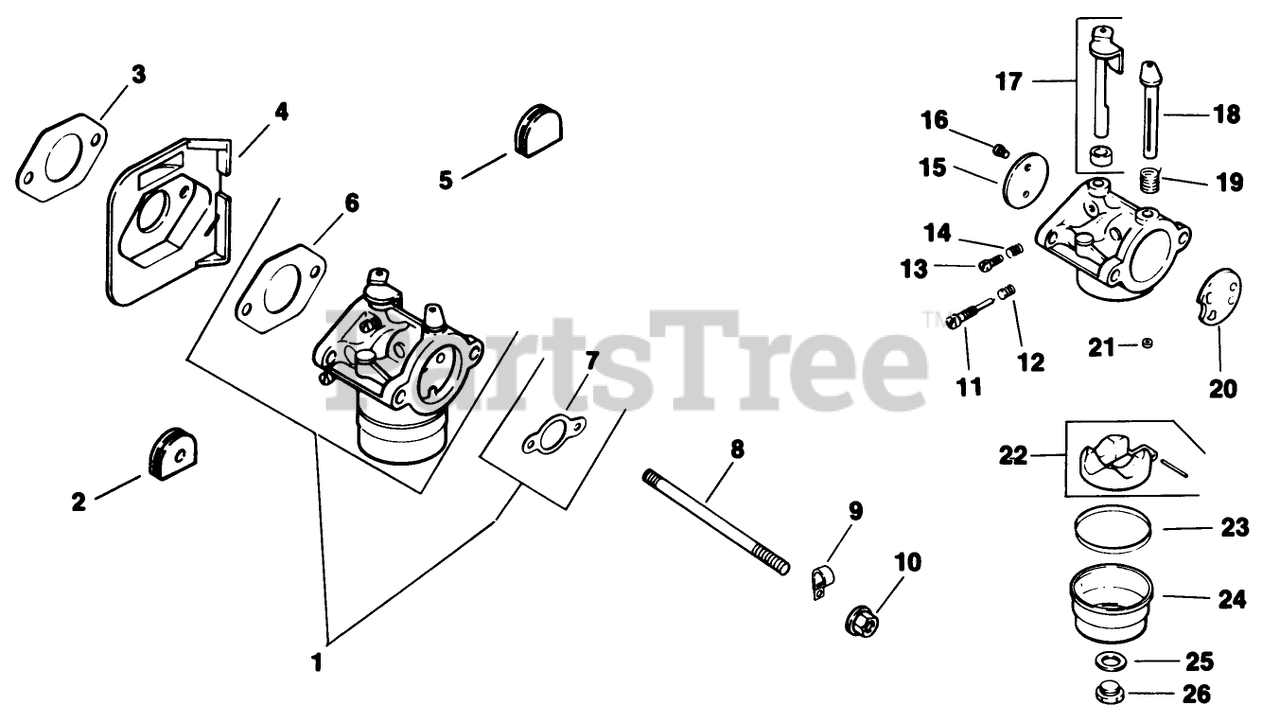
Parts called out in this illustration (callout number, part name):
1	Kit-Carb INCL 4/6/21 -36 (Only On: 72042,72043,72062,72063)
2	Grommet (Only On: 72042, 72063, 72062, 72043)
3	Gasket-Carburetor (Only On: 72042, 72063, 72062, 72043)
4	Deflector-Heat (Only On: 72042,72043,72062,72063)
5	Grommet
6	Gasket-Carburetor (Only On: 72042, 72063, 72062, 72043)
7	Gasket-Air Cleaner (Only On: 72042, 72043, 72062, 72063)
8	Stud M6x1.0x110 (Only On: 72042,72043,72062,72063)
11	Needle-Idle Fuel Adjust (Only On: 72042, 72063, 72062, 72043)
12	Spring-Idle Fuel (Only On: 72042, 72063, 72062, 72043)
13	Screw-Idle Speed Adjust (Only On: 72042,72043,72062,72063)
14	Spring-Idle Fuel (Only On: 72042, 72063, 72062, 72043)
15	Plate-Throttle (Only On: 72042,72043,72062,72063)
16	Screw-Throttle Plate (Only On: 72042,72043,72062,72063)
17	Shaft-W/Lever Seal (Only On: 72042, 72063, 72062, 72043)
18	Shaft-Choke (Only On: 72042. 72063, 72062, 72043)
19	Spring-Choke Return (Only On: 72042,72063, 72062, 72043)
20	Plate-Choke (Only On: 72042, 72063, 72062, 72043)
21	Jet-Main
22	Kit-Float (Only On: 72042,72043,72062,72063)
23	Gasket-Bowl (Only On: 72042,72043,72062,72063)
24	Bowl-Fuel (Only On: 72042, 72063, 72062, 72043)
25	Gasket-Bowl Screw (Only On: 72042, 72063, 72062, 72043)
26	Screw-Fuel Bowl (Only On: 72042, 72063,72062, 72043)
